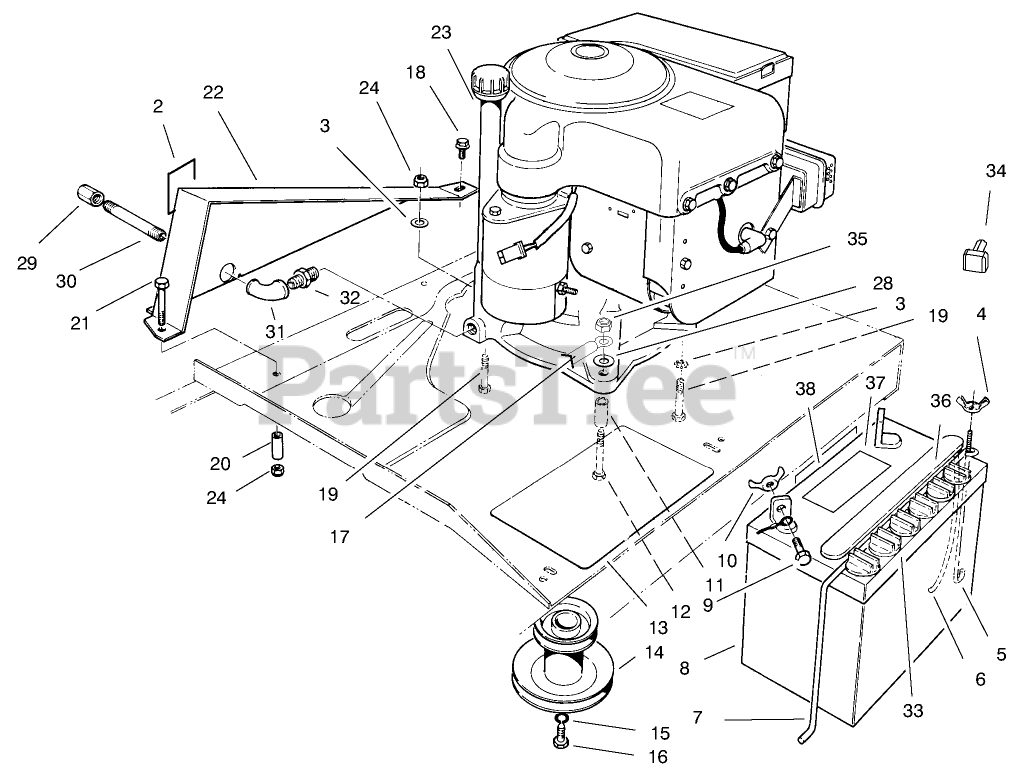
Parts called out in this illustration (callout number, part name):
1	CLAMP-HOSE
2	FUEL PUMP
3	NUT-HEX
4	PULSE LINE
5	CLAMP-HOSE
6	AIR CLEANER HOSE
7	Engine
8	BODEN CLIP BRKT
9	CLAMP-BODEN
10	WASHER-LOCK
11	SCREW
12	SCREW
13	SCREW-HH
14	REAR SHIELD WA B
15	SPACER HEAT SHIELD
16	Shield Exhaust
17	EXHAUST PIPE
18	WASHER-PLAIN
19	MUFFLER BRACKET B
20	WASHER-LOCK
21	NUT-HEX
22	Decal-Hot
23	Locknut
24	10-24 X 5/8 PAN HD MS
25	SCREW-HH
26	WASHER-FLAT
27	MUFFLER BRKT B
28	SCREW THD 1/4 20 5/8
29	Top Heat Shield
30	MUFFLER CLAMP
32	LH SIDE HT SHIELD B
33	SCREW-HH
35	Bottom Heat Shield
36	Bracket Heat Shield
37	SCREW-HH
38	WASHER-LOCK
39	WASHER-LOCK
40	WASHER-FLAT
41	RUBBER MOUNT
42	SCREW-HH
43	REAR ENGINE MT B
44	SCREW-HH
45	WASHER-LOCK
46	NUT-LOCK, NI
47	WASHER
48	NUT-HEX
49	SCREW-HH
50	NUT-HEX
51	WASHER-LOCK
52	WASHER-FLAT
53	RUBBER MOUNT
54	ENGINE BASE WA
55	SCREW-HH
56	ENGINE PULLEY BO
57	SPACER-RUBBER COUPLNG
58	COUPLING-RUBBER
59	WASHER-FLAT
60	SCREW-HH
61	DRIVE COUPLING WA B
62	NUT-HEX
63	SPACER-COUPLING
64	SCREW-HSH
65	SCREW-HH
66	Screw-Outlet
67	HOSE-FUEL
68	1.875 ID HOSE CLAMP
69	FiIter Gas
70	HOSE-FUEL
71	SCREW-HH
72	FITTING
73	FUEL LINE
